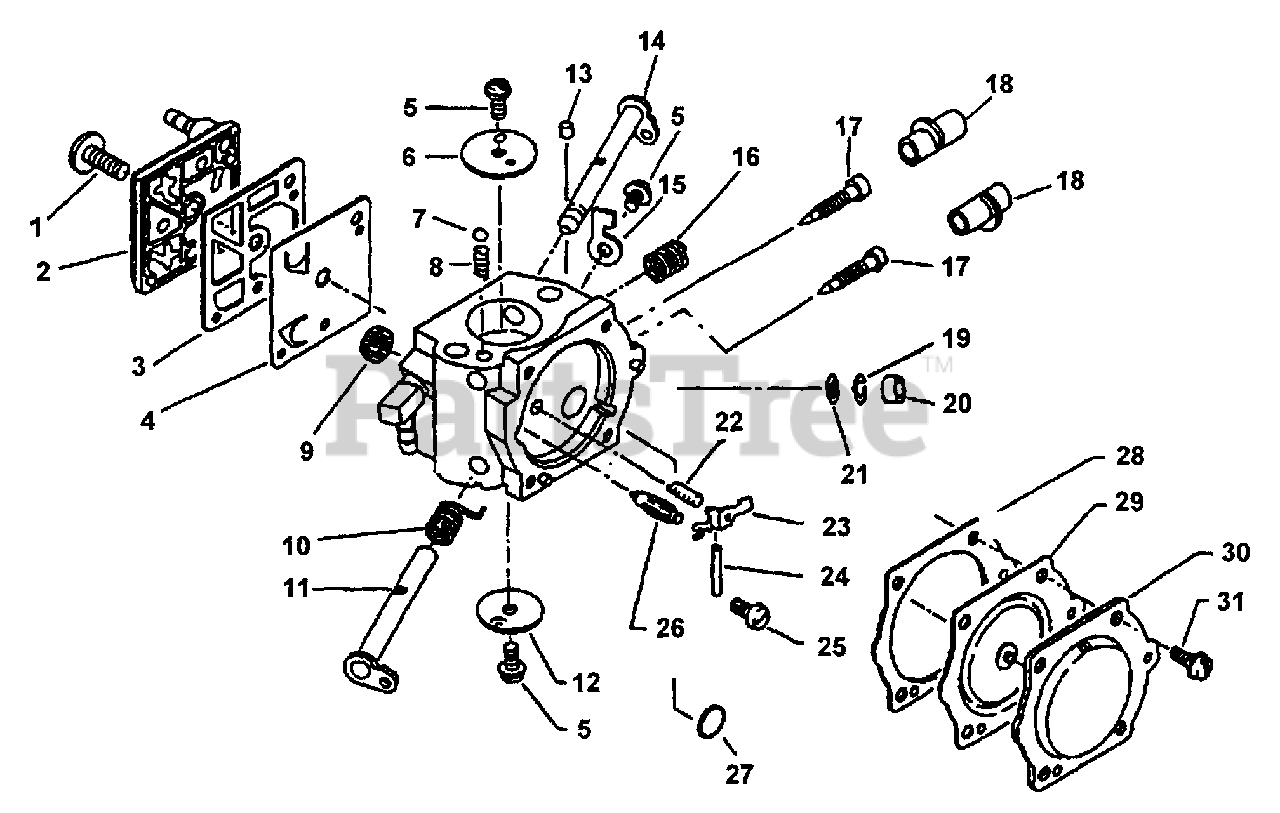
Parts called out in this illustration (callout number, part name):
1	SCREW, PUMP COVER
2	COVER, PUMP
3	GASKET, PUMP
4	DIAPHRAGM, PUMP
6	VALVE, CHOKE
7	BALL, CHOKE
9	STRAINER
10	SPRING, THROTTLE RETURN
11	SHAFT, THROTTLE
12	VALVE, THROTTLE
14	SHAFT, CHOKE
15	STOP, THROTTLE
16	SPRING, IDLE ADJUST
17	NEEDLE - MIXTURE
18	CAP, LIMITER
19	RING, RETAINING
20	PLUG, WELCH
21	STRAINER
22	SPRING, METERING LEVER
23	LEVER, METERING
24	PIN, METERING LEVER
25	SCREW, METERING LEVER PIN
26	VALVE, INLET NEEDLE
27	PLUG, WELCH
28	GASKET, METERING
29	DIAPHRAGM, METERING
30	COVER, METERING
31	SCREW
